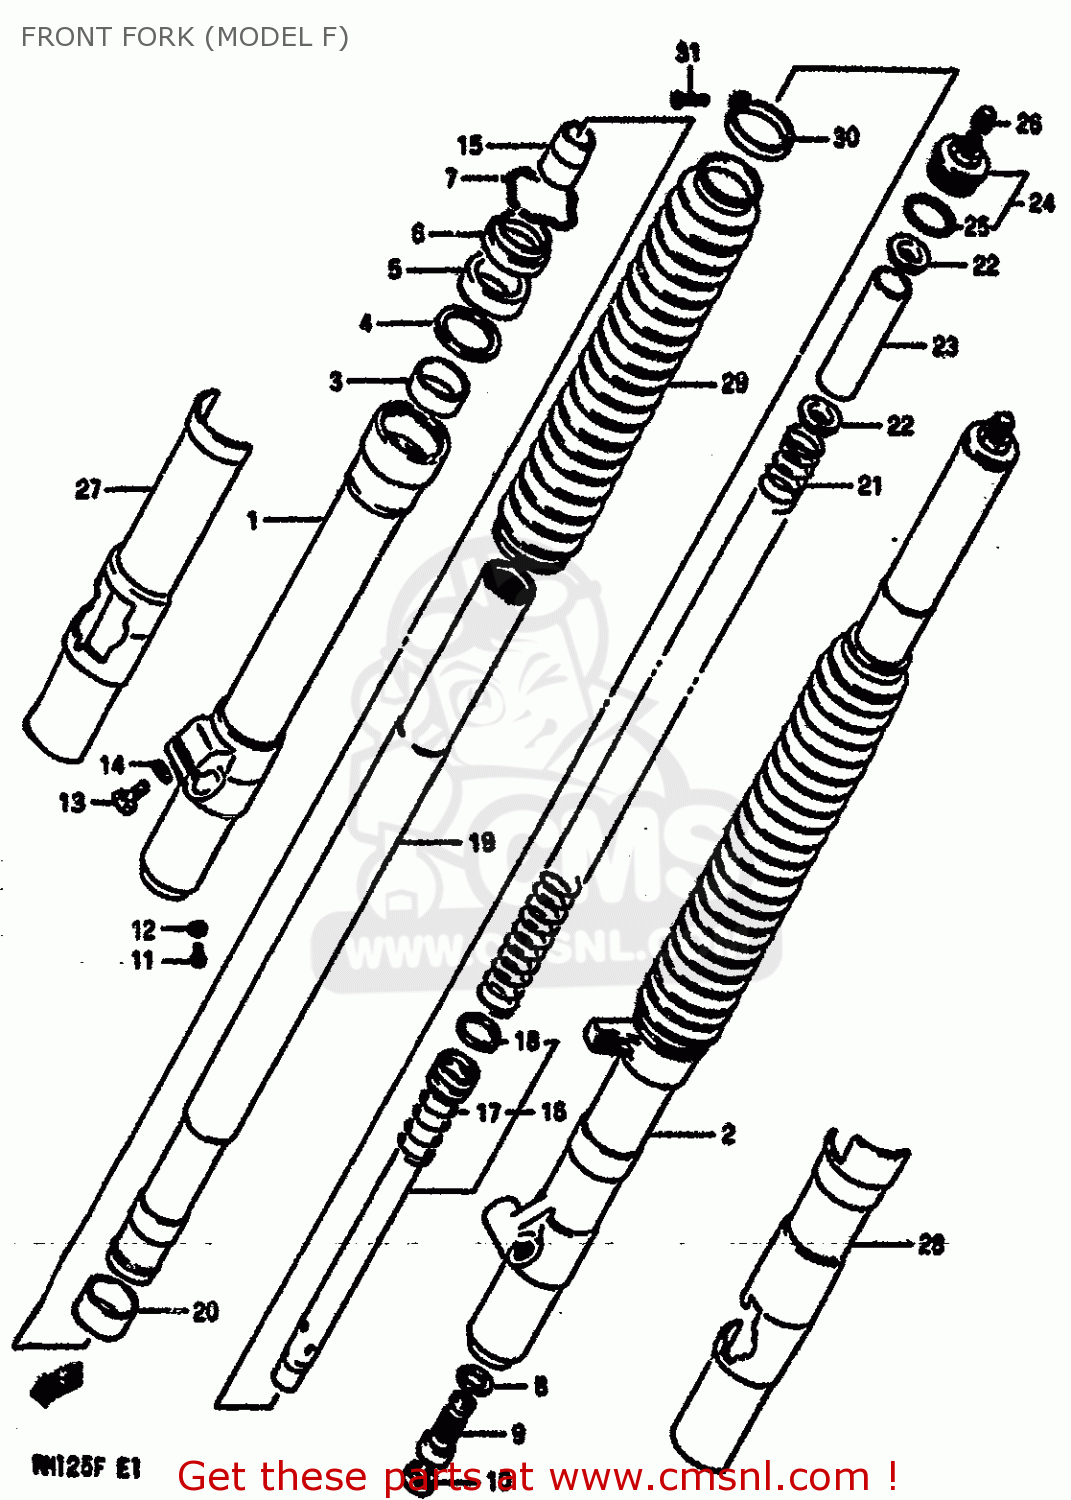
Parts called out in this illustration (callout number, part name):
1	TUBE,OUTER,RIGHT
2	TUBE,OUTER,LEFT
3	METAL,SLIDE
4	WASHER
5	SEAL,OIL
6	SEAL,DUST
7	RING,STOPPER
8	GASKET,FORK CYLINDER
9	VALVE,DF
10	CAP,FRONT FORK DF
11	SCREW 4X6
12	GASKET,DRAIN,PLUG (NAS)
13	BOLT (8X30)
14	WASHER,LOCK,8.
15	PIECE,FRONT FORK OIL LOCK
16	CYLINDER
17	SPRING,REBOUND
18	RING,FRONT FORK PISTON
19	TUBE,FORK,INNER
20	PISTON
21	SPRING,FRONT FORK
22	GUIDE,FRONT FORK SPRING
23	SPACER,FRONT FORK SPRING
24	CAP,FORK INNER TUBE
25	O RING
26	CAP
27	PROTECTOR,RIGHT
28	PROTECTOR,LEFT
29	BOOT,FRONT FORK COVER
30	BAND,BOOT,UPPER
31	SCREW 4X10
